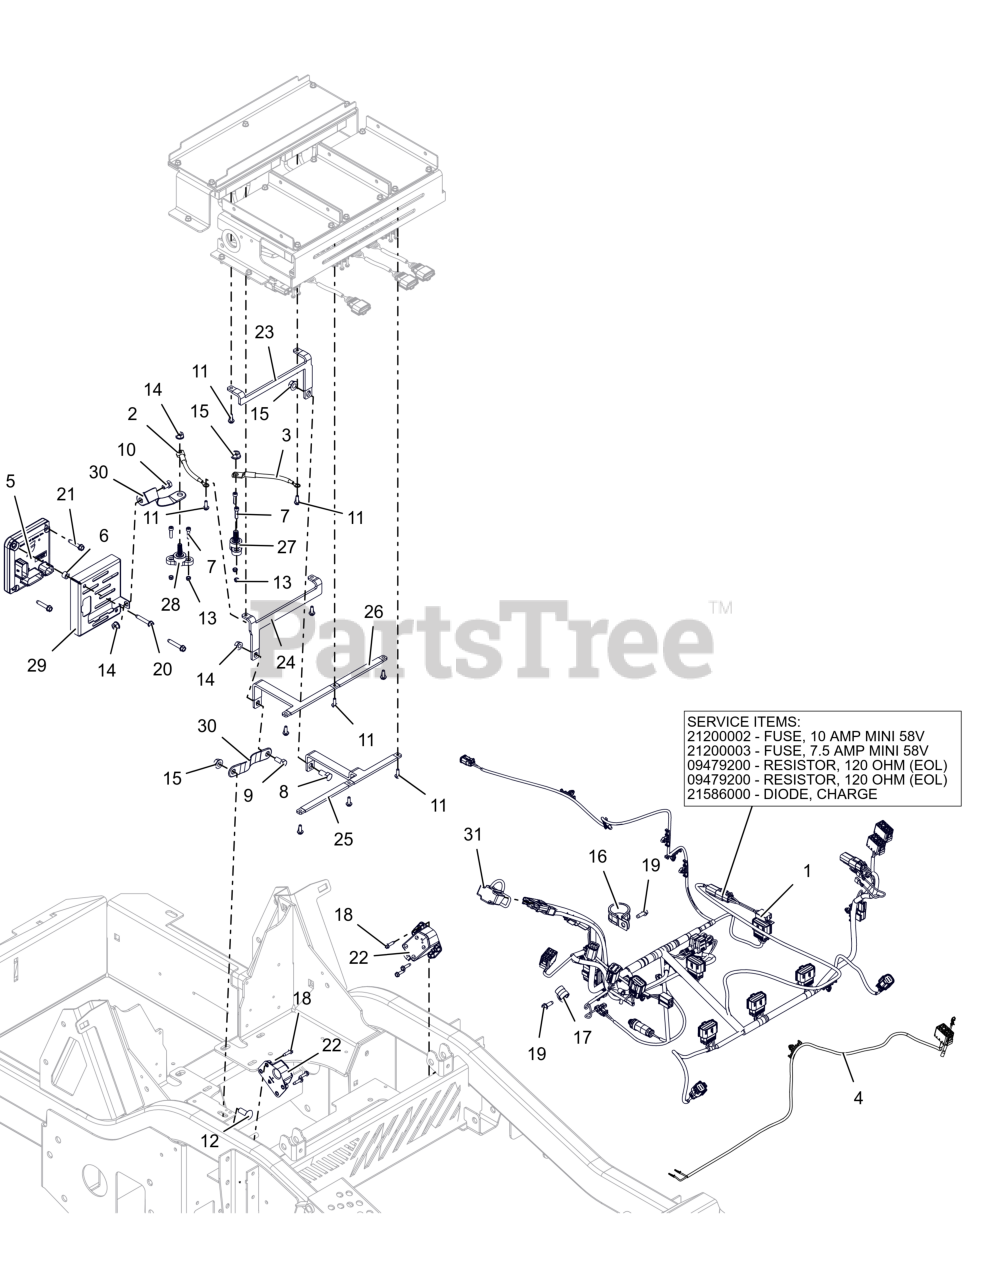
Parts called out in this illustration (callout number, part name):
1	HARNESS, PTEV MAIN WIRE
1	FUES, 10 AMP MINI 58V
1	FUSE, 7.5 AMP MINI 58V
1	RESISTOR, 120 OHM (EOL)
1	DIODE, CHARGE
2	CABLE, GROUND
3	CABLE, POSITIVE
4	HARNESS- ECO MODE ACCESSORY
5	KIT, MY23 PTEV VCM RD REPLACE
6	SPCR, .334X.500X.324
7	SCR, SKH M5-.8 X 20 GR12.9 ROHS
8	BLT,HEX .38-16X.75 G5 ZCC
9	BLT,HEX .31-18X.75 G5 ZCC
10	BLT, HEX .31-18X.50 GR5 ZCC
11	BLT,HEX M5-.8X16 EP30 G8.8 ZCC
12	BLT,RHSSN .38-16X1.00 G5 ZCC
13	NUT, LK-NYL M5-0.8 GR8.8 ZC120
14	NUT,LK-CTR-FLG .31-18 GF ZCC
15	NUT-LK-CTR-FLG .375-16 GF ZCC
16	CLAMP, CUSHIONED STEEL 1.25
17	CLAMP, CUSHIONED STEEL
18	SCR, TAP #10-24X.75 HWH ZCC
19	SCR,TAP .25-20X.75 HWH TR ZCC
20	SCR,TAP .25-20X1.50 HWH TR ZCC
21	SCR-TAP .25-20X1.25 HWH TR ZCC
22	SENSOR, STEERING
23	BAR, BUSS -POS. WHL
24	BAR, BUSS-NEG. WHL
25	BAR, BUSS-POS
26	BAR, BUSS -NEG
27	STUD, POSITIVE POWER
28	STUD, NEGATIVE POWER
29	COVER, VCMA ALUMINUM
30	STRAP, GROUND
31	COVER, CONNECTOR DUST
